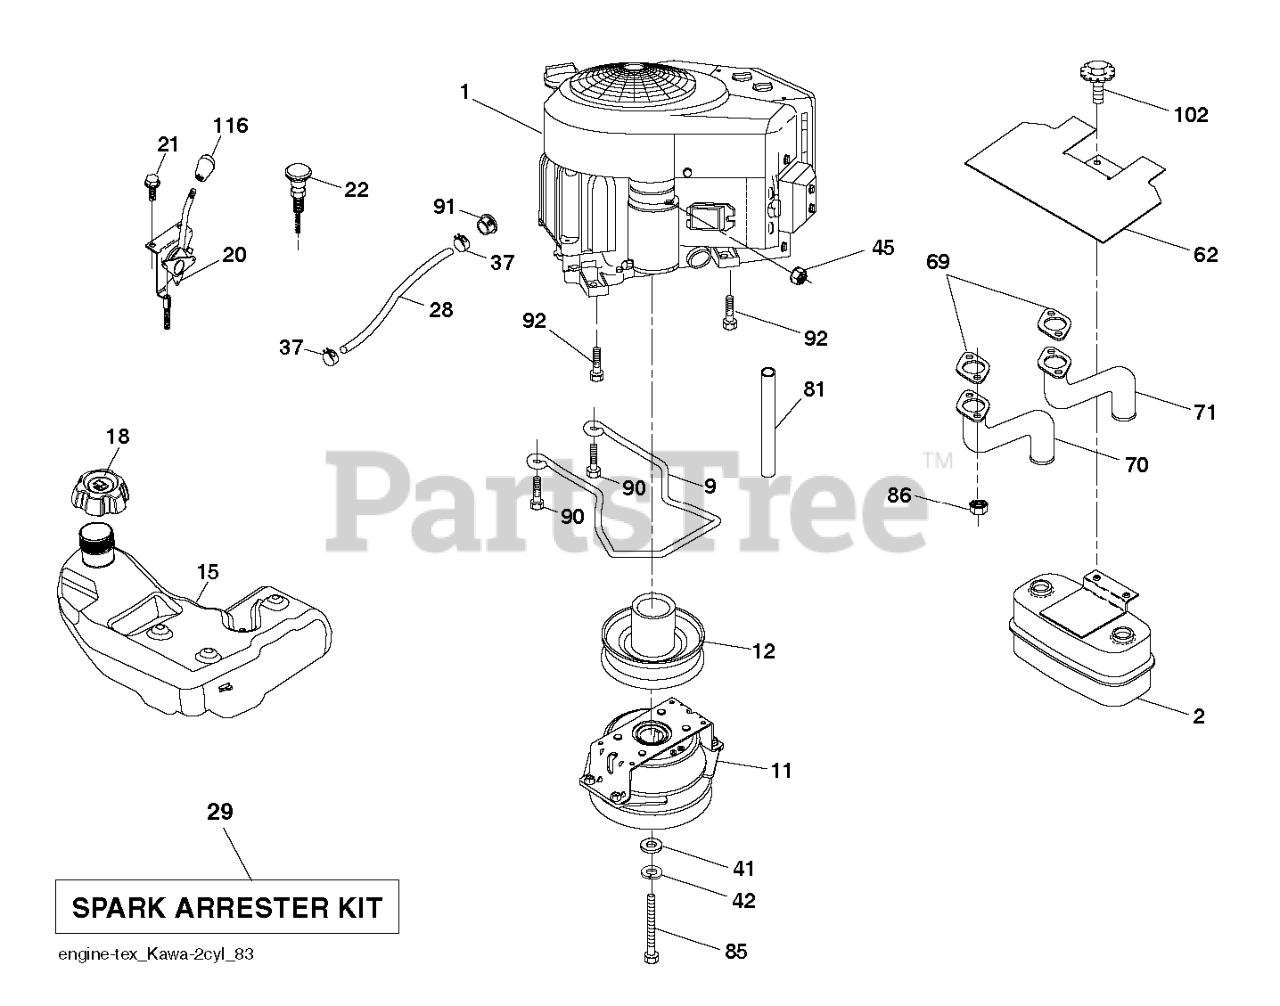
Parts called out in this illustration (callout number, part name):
2	MUFFLER.ASM.TWIN.MNTG.BRACKET
11	CLUTCH.OGURA.4.4PD.GT1.5-EH13V
12	PULLEY.ENGINE.TUFFTORQ
15	FUEL TANKS
18	FUEL CAP
18	CAP ASSY FUEL 3" GRAY
20	CONTROL.THROTTLE.PRO.
21	SCREW.#10X.750
22	CONTROL, CHOKE
28	LINE.FUEL.64"REAR.EMIS
29	KIT.SPARK ARRESTOR 794945 B&S
37	HOSE CLAMP
62	SHIELD.HEAT.MUFFLER
70	TUBE.EXHAUST.LH.FR961/FR730
71	TUBE.EXHAUST.RH.FR961/FR730
81	TUBE, DRAIN OIL ASM.
85	CLUTCH BOLT7/16-20X3.5 GR524HR
86	NUT.HEX.FLANGE.TOPLOCK
90	SCREW 3/8-16X1
91	BUSHING.1.375OD
92	SCREW 3/8-16X1
102	SCREW
116	KNOB - SHIFT
